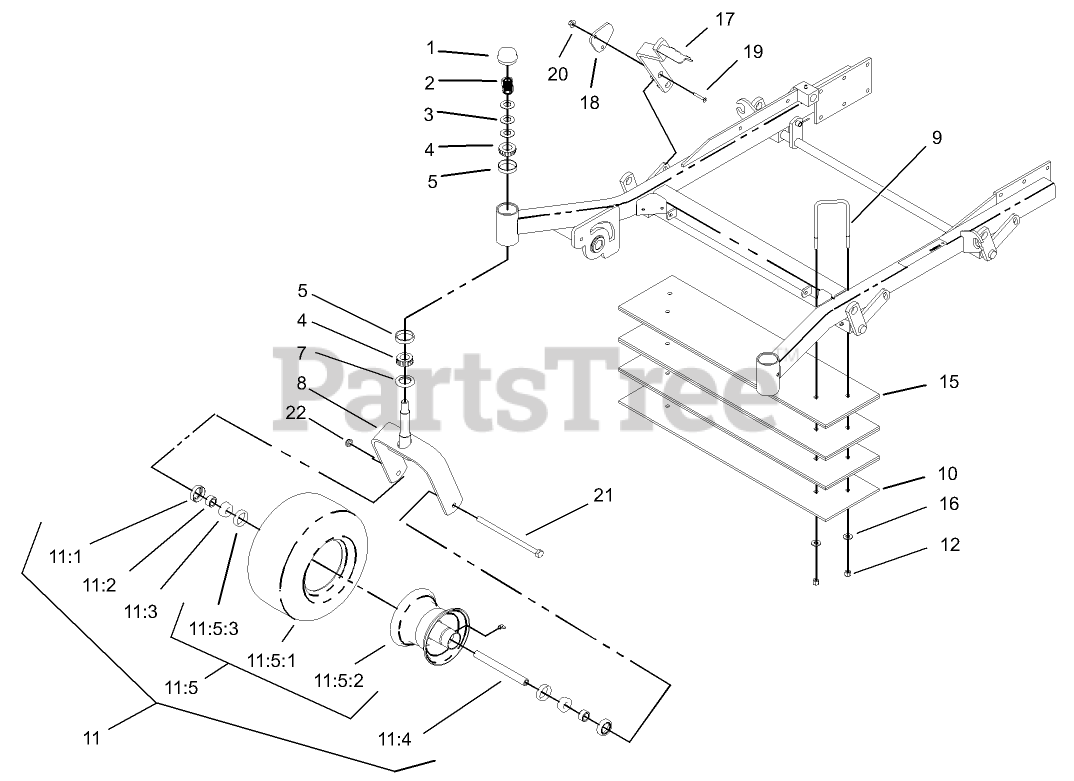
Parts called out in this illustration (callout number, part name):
1	CAP-GREASE
2	NUT-LOCK, NI
3	WASHER-BELLVILLE
4	BEARING-CONE, TAPERED
5	BEARING-CUP, TAPERED
7	SEAL-GREASE
8	CASTER-FORK
9	U-BOLT
10	BAR-WEIGHT
11	CASTER WHEEL ASM
11:1	SEAL-BEARING
11:2	SPACER-BEARING
11:3	BEARING-CONE, TAPER
11:4	SPACER-CASTER, FRONT
11:5	WHEEL AND TIRE ASM
11:5:3	BEARING-CUP
12	NUT-LOCK, NI
15	WEIGHT BAR ASM
16	WASHER-FLAT
17	LEVER-LIFT, DECK
19	SCREW
20	NUT-HF
21	Screw-HH
22	NUT-LOCK, NI
